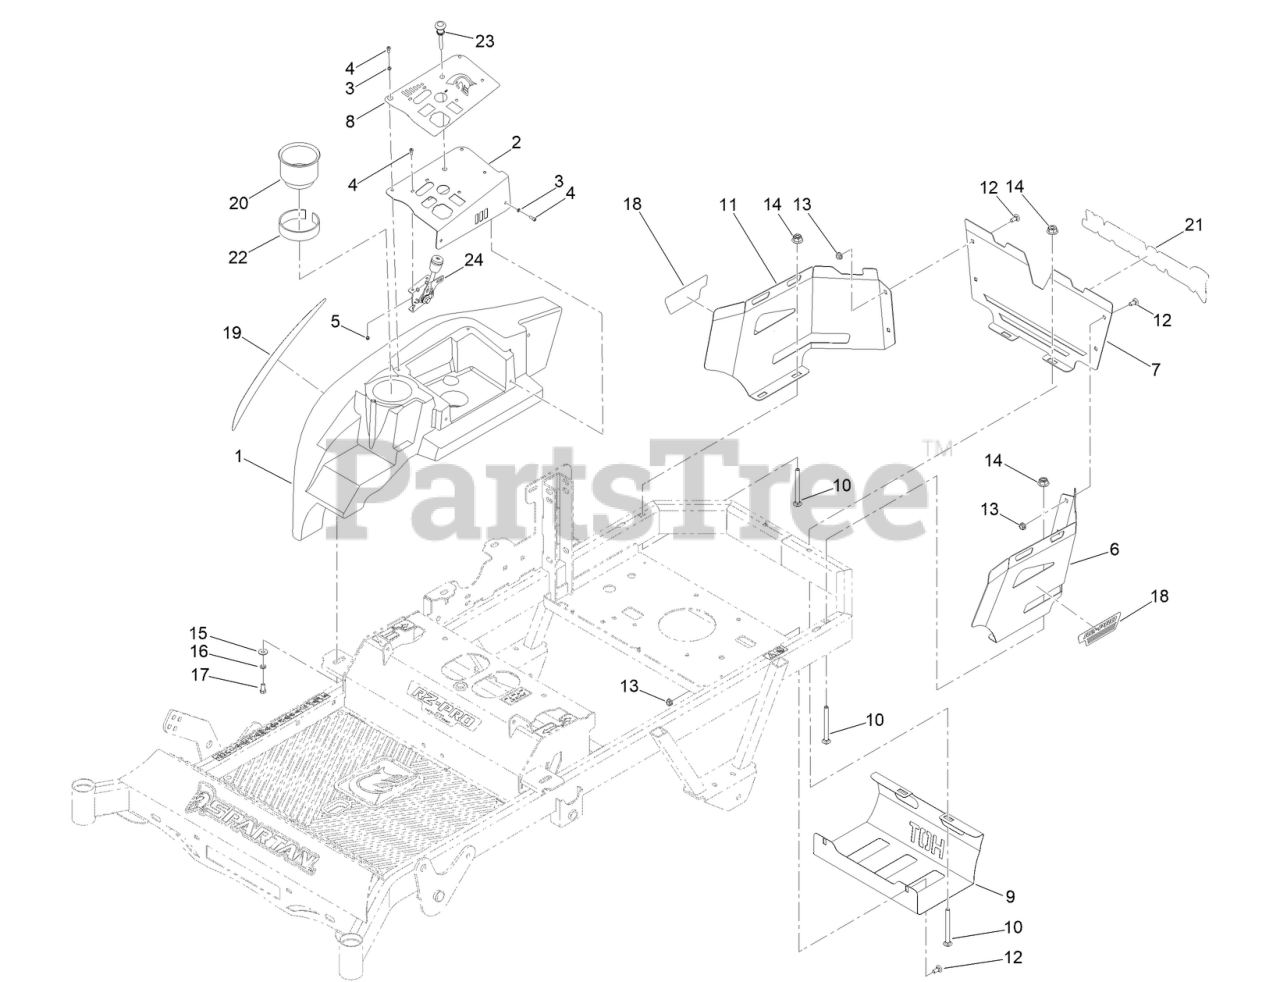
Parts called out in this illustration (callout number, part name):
1	CONSOLE W/ CUPHOLDER
2	GAS TANK CONSOLE INDIV CONTROLS PAINT
3	#10 SPLIT LOCKWASHER 18-8 SS
4	10-24 X 1/2 SOCKET C/S 18-8 SS
5	NUT-LOCK
6	2021 RZC RR COVER LT SIDE PAINTED
7	2021 RZC RR COVER CNTR PLATE PAINTED
8	RZ-C THRU RZ-PRO KEYSWITCH CONSOLE DECAL
9	RZ MWR MUFFLER GUARD PAINTED
10	3/8-16 X 4 CARRIAGE BOLT ZINC
11	2021 RZC RR COVER RT SIDE PAINTED
12	BOLT-CARR
13	NUT-HF
14	3/8-16 NYLON INSERT FLANGE L/NUT YZ
15	WASHER-FLAT
16	WASHER-LOCK
17	SCREW-HH
18	DECAL-MODEL
19	2021 RZ FUEL TANK DECAL RT SIDE
20	CUP HOLDER
21	MWR FT SPARTAN LOGO
22	TAPE-FOAM
23	MWR CHOKE CABLE ASSM
24	MWR THROTTLE CABLE ASSY W / HANDLE
